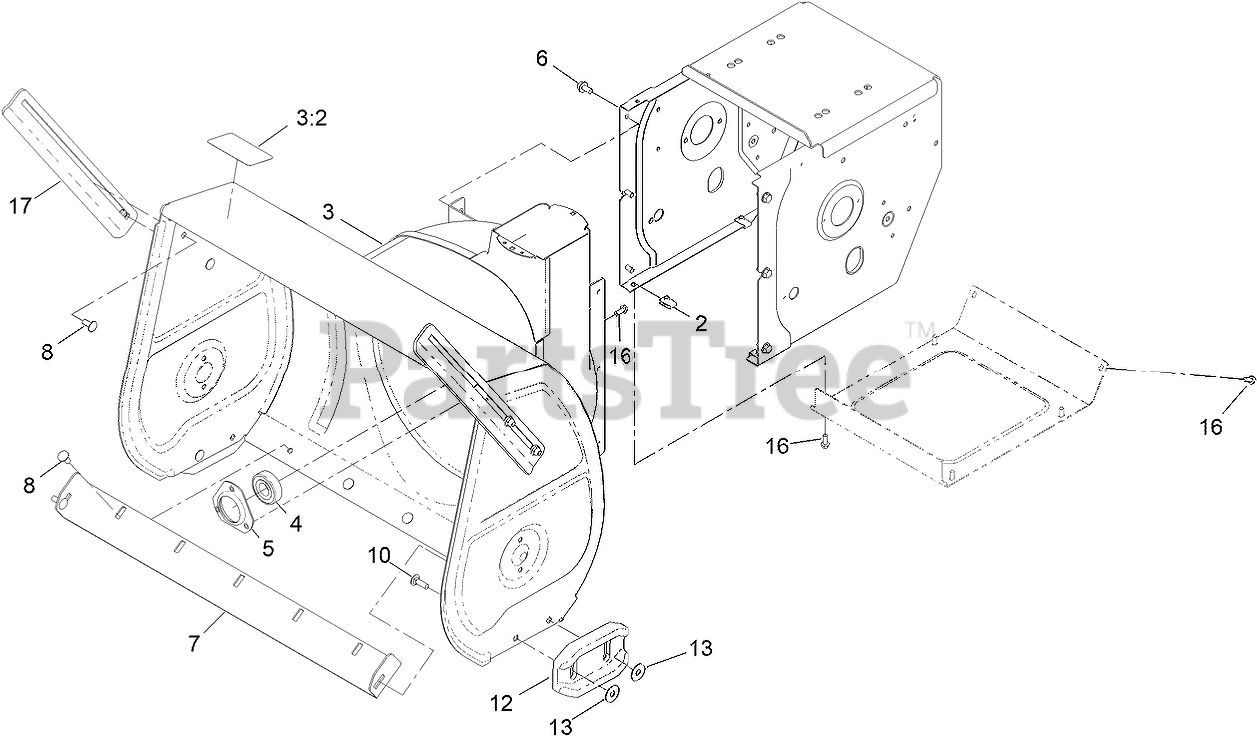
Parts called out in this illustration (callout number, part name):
3	AUGER HOUSING ASM
3:2	DECAL-DANGER, AUGER
4	BEARING-BALL
5	RETAINER-BEARING
6	SCREW-HWHTF
7	BLADE-SCRAPER
8	BOLT-CARR
10	BOLT-CARR
12	SKID-CAST
13	WASHER-FLAT
16	SCREW-HWH
17	BREAKER-DRIFT, SIDE
